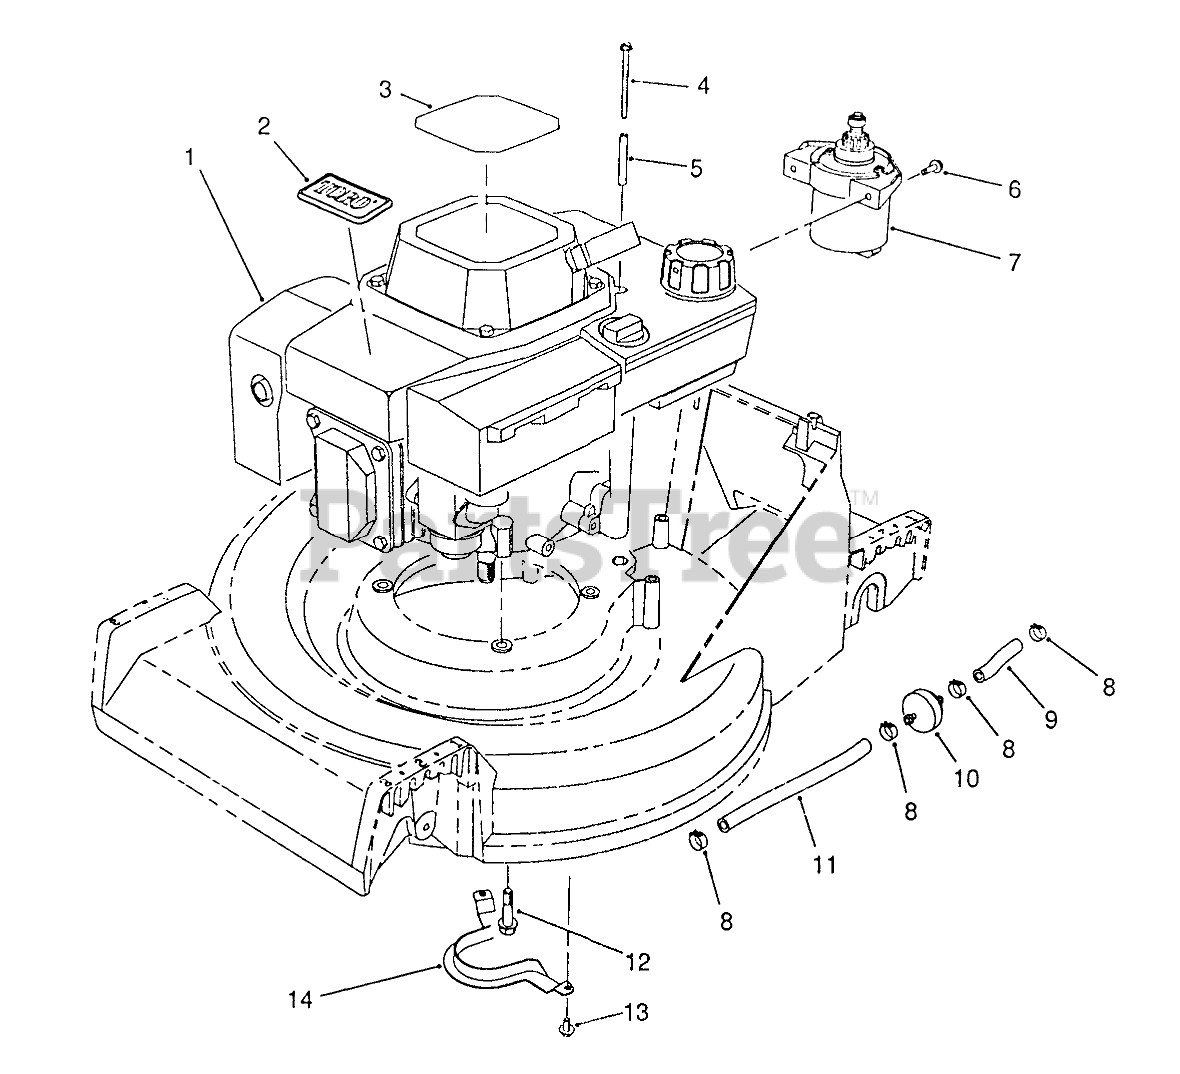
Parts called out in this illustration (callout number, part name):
1	Engine-OHV
2	TORO LOGO PLT
3	DECAL - OHV RECOIL
3	DECAL-HV INT'L
4	THRD FORMING SCREW
5	TUBULAR SPACER
6	SCREW
7	STARTER MOTOR ASM
8	CLAMP-FUEL LINE
9	LINE-GAS
10	FILTER-FUEL
11	HOSE-FUEL
12	SCREW-HWHTF
13	SCREW-HWHTF
14	Guide-Belt
